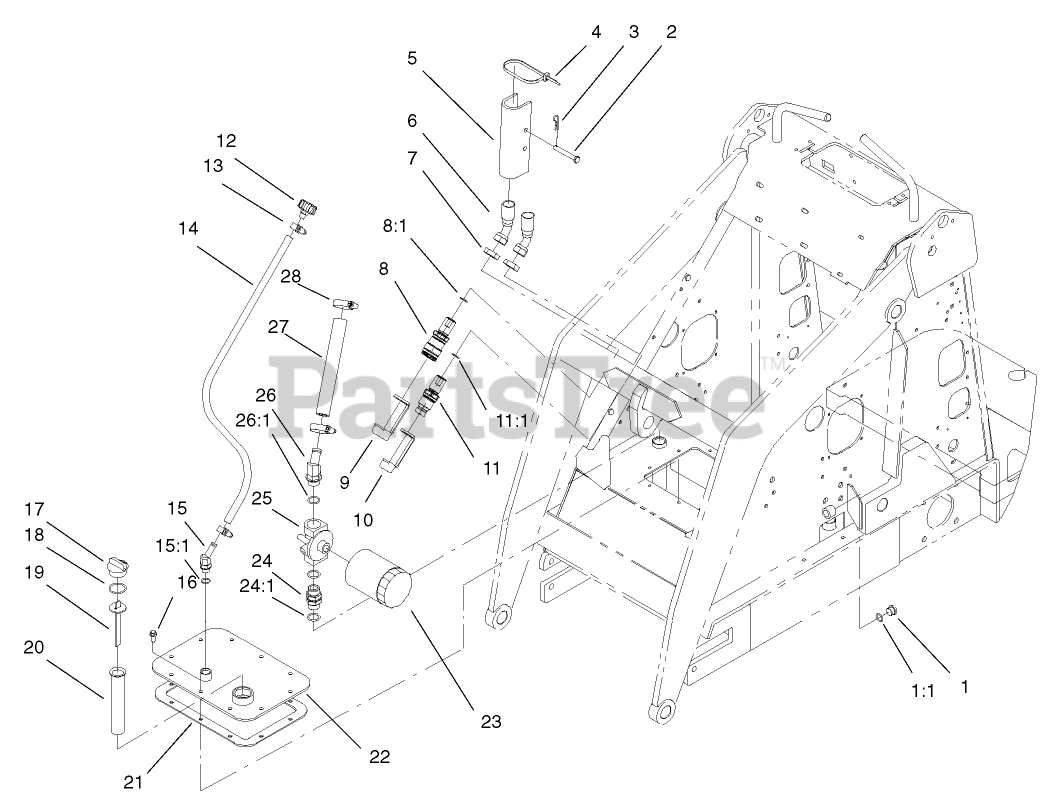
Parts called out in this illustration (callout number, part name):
1	PLUG-HEX
1:1	O-RING
2	PIN-CLEVIS
3	PIN-HAIR
4	TIE-CABLE
5	LOCK-CYLINDER
6	HOSE-HYD
7	NUT-LOCK, BULKHEAD
8	BULKHEAD COUPLER ASM
8:1	O-RING
8:2	SEAL KIT
9	CAP-DUST, COUPLER
10	CAP-DUST, NIPPLE
11	BULKHEAD NIPPLE ASM
11:1	O-RING
11:2	SEAL KIT
12	BREATHER
13	CLAMP-HOSE
14	HOSE-VENT
15	FITTING-HYD, 45 DEG
15:1	O-RING
16	SCREW
17	PLUG-PLASTIC
18	O-RING
19	DIPSTICK-OIL
20	FILTER-SCREEN
21	GASKET-COVER
22	COVER
23	FILTER-OIL, TRANSMISSION
24	FITTING-THREAD, STRAIGHT
24:1	O-RING
25	HEAD-FILTER
26	ELBOW-45 DEG
26:1	O-RING
27	HOSE-HYD
28	CLAMP-HOSE
